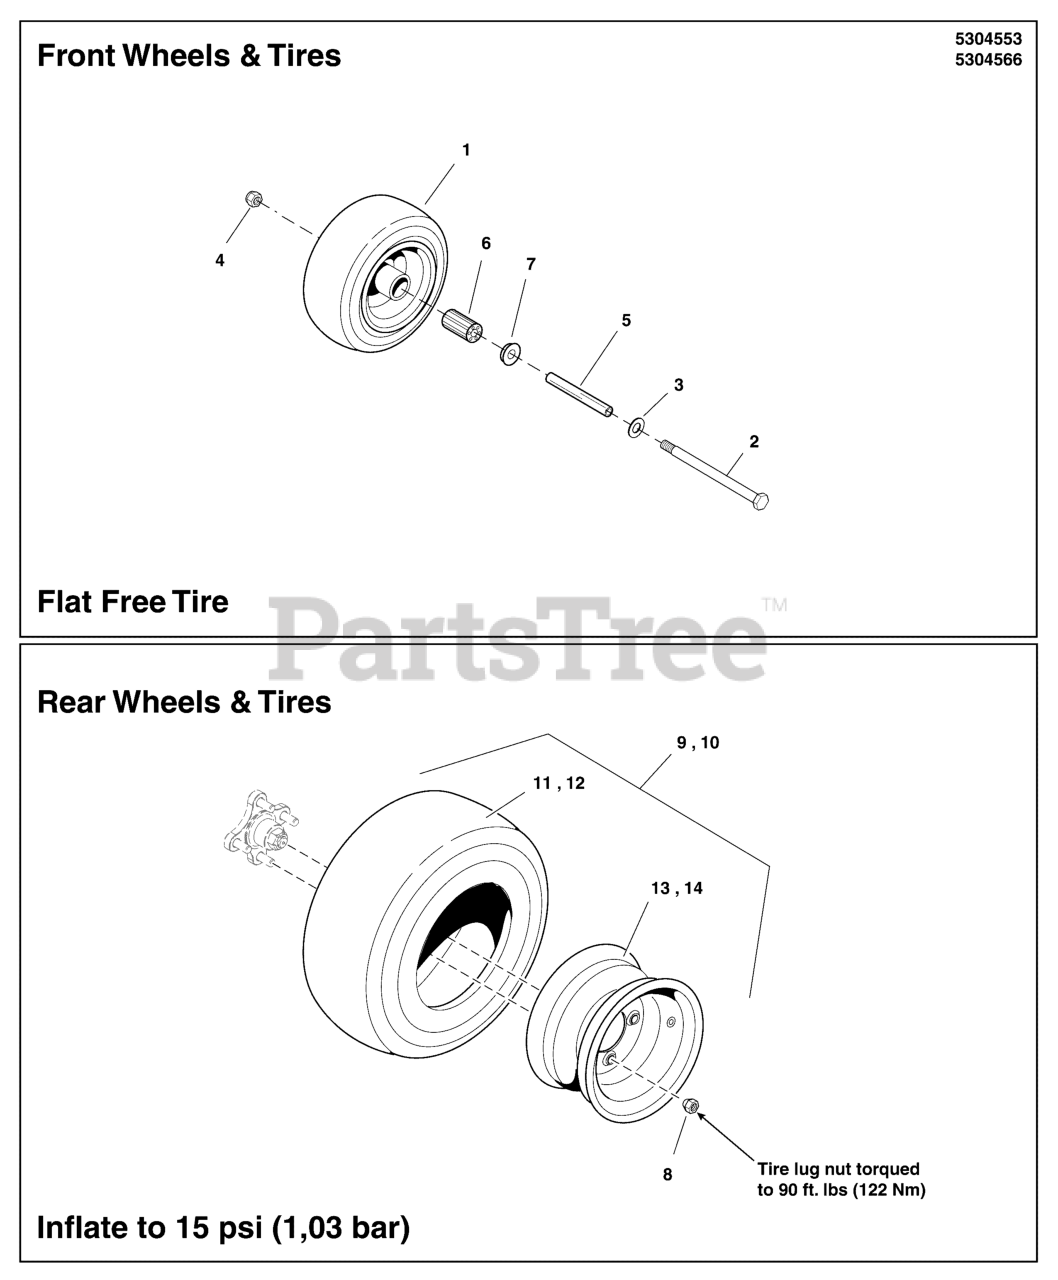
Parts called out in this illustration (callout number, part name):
1	TIRE ASSM, 11 X 4 - 5, FF / CB
2	BOLT, 1/2-13 X 7 GD5 CZ
3	WASHER, 1/2 SAE
4	NUT, Hex Flange, Nylock, 1/2-13
5	CASTER AXLE DDSH
6	BEARING, ROLLER
7	BEARING, RETAINER
8	NUT, 1/2-20, FOR WHEEL BOLT SILVER
9	TIRE WHEEL ASM, 23 X 8.5-12, TURF MASTER
10	TIRE WHEEL ASM, 23 x 10.5-12, TURF SMART
10	TIRE/WHEEL ASM, 23X10.5-12, TURF MASTER
11	TIRE, 23 X 8.5-12NHS, TURF MASTER
12	TIRE, 23 X 10.5-12NHS, TURF SMART
12	TIRE
13	WHEEL, 12.0 X 7.0, 4/4.0", SILVER
14	WHEEL ASM, 12 X 8.5-12, 1.87OS, SLVR
